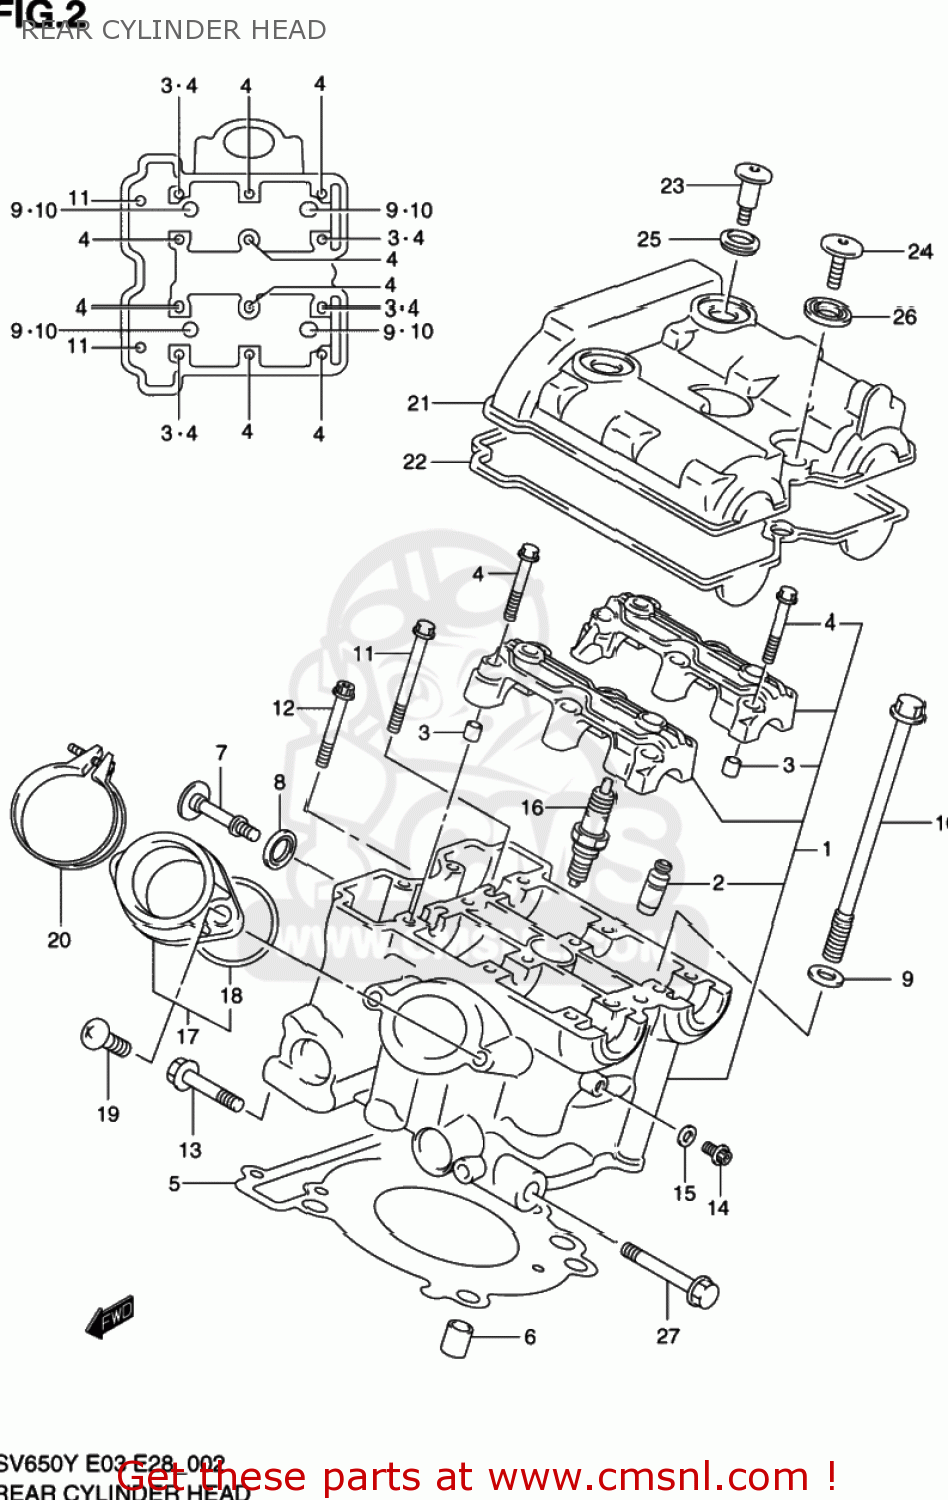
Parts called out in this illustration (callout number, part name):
1	HEAD ASSY,CYLINDER RR
2	GUIDE,VALVE
3	PIN(6.2X8X11)
4	BOLT(6X39)
5	GASKET,CYLINDER HEAD (NAS)
6	PIN
7	BOLT,CYL HEAD SIDE FACE
8	WASHER,HEAD COVER
9	WASHER(10.5X19X2)
10	BOLT(10X160)
11	BOLT(6X70)
12	BOLT
13	BOLT
14	BOLT
15	GASKET(5.8X13X1.2) (NAS)
16	PLUG,SPARK(CR8E)
17	PIPE ASSY,INTAKE RR
18	O RING(D:2.4,ID:47X42)
19	SCREW ,6X16
20	CLAMP
21	COVER,CYLINDER HEAD RR
22	GASKET,CYLINDER HEAD COVER (NAS)
23	BOLT(7X17.5)
24	BOLT(7X31)
25	WASHER(10.6X25.5X2.3)
26	CUSHION,HEAD COVER BOLT
27	BOLT
